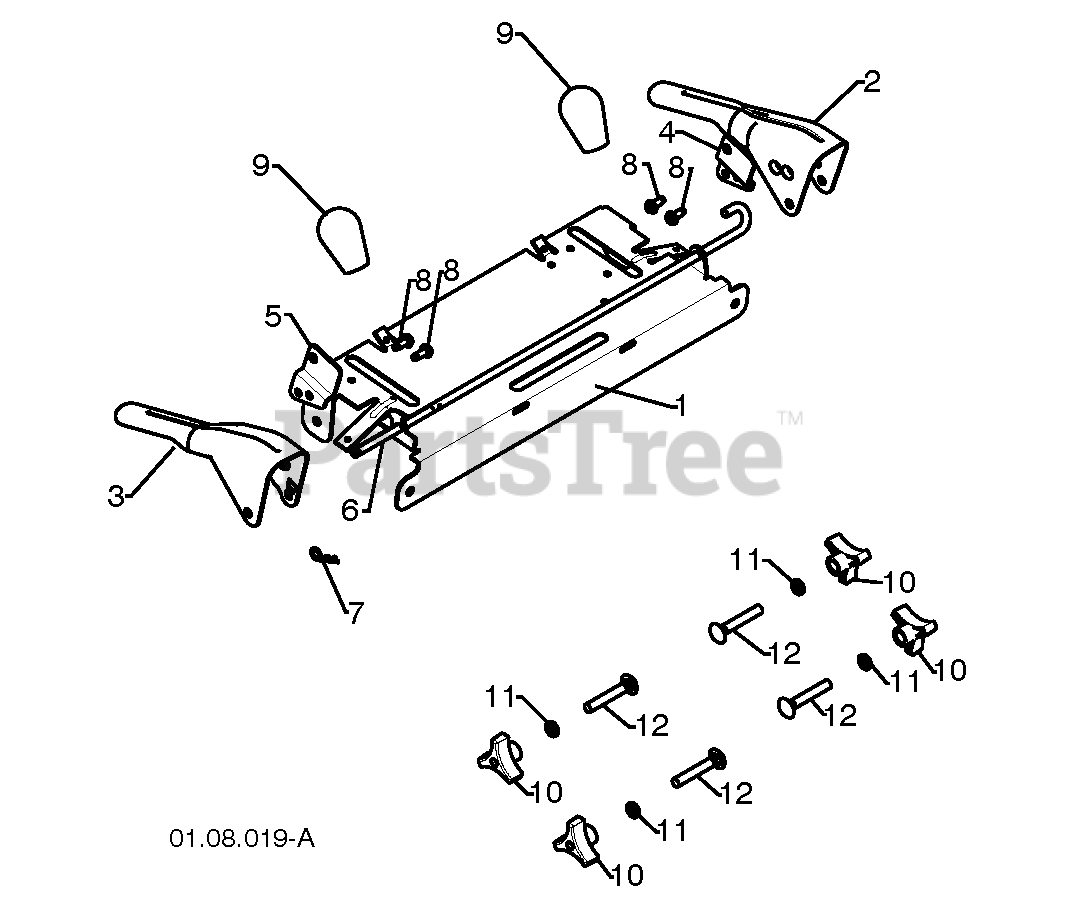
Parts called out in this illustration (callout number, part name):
1	PANEL.CONTROL.SNOW.BL
2	LEVER.CONTROL.LH.BLACK
3	LEVER.CONTROL.RH.GREY
4	BRACKET.ROD.TRACT.LH.ZINC
5	BRACKET.ROD.IMP.RH.ZINC
6	BAIL.CONTROL.INTERLOCK
7	SPRING RETAINER
8	SCREW 14-20 X 5/8
9	KNOB.OVERMOLD.DS.HUSQVARNA/BLK
10	KNOB.HANDLE.3/8.TRI-POINT.BLAC
11	WASHER
12	BOLT 3/8-16 X 2-1/4
